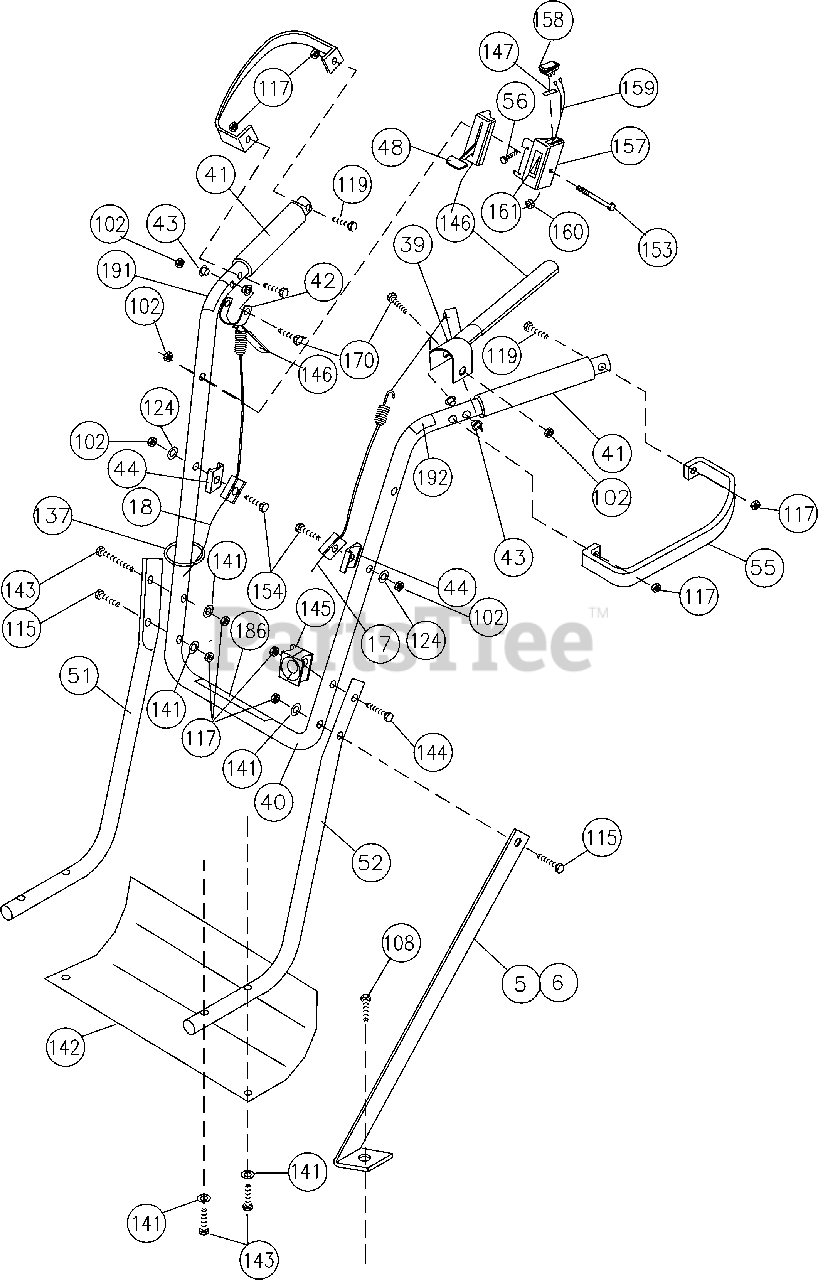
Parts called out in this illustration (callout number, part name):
5	Handle Brace Left
6	Handle Brace Right
17	Cable Clutch Blade BC2402
18	Cable Clutch Drive BC2402
39	Lever Control Blade
40	Handle Upper BC2402
41	Grip Handle 1” ID x 7.5”
42	Lever Control Clutch
43	Bushing Lever Control
44	Fitting Mount Cable
48	Throttle Control, Including Cable
51	Handle Lower RH BC2402
52	Handle Lower LH BC2402
55	Guard Hand BC2402
56	Screw Cap 8-3/8 HWH Type B
102	Nut Lock 1/4-20
108	Screw Cap 5/16-18 x 2-3/4”
115	Screw Cap 5/16-18 x 2"
117	Nut Lock 5/16-18
119	Screw Cap 5/16-18 x 1-1/2”
124	Washer 1/4” FC
141	Washer 5/16” FC
142	Bracket Clutch Cable Guard
143	Screw Cap 5/16-18 x 1-3/4”
144	Screw Cap 5/16-18 x 2-1/2”
145	Guide Rope (Honda only)
146	Grip Lever
147	Part Not Applicable on this model
153	Screw Cap 1/4-20 x 3”
154	Screw Cap 1/4-20 x 2”
157	Switch Box Assy BC (includes throttle cable)
158	Switch Toggle, ON/OFF
159	Harness Assy
160	Bushing Strain Relief
161	Label Throttle
170	Bolt Shoulder 5/16-18 x 1-1/2”
186	Label Shift BC2402
191	Label Clutch Drive
192	Label Clutch Blade
